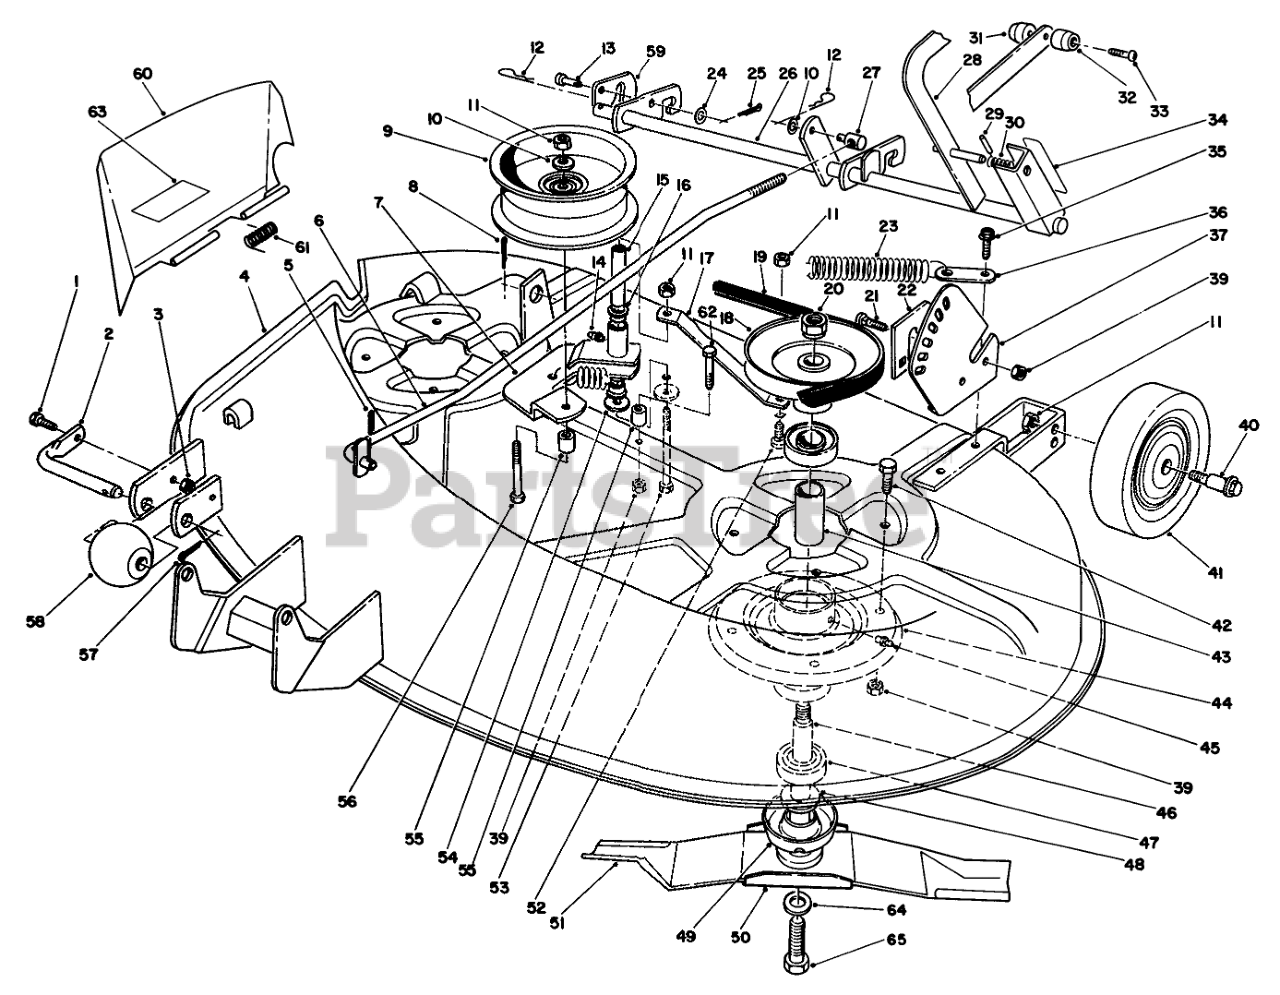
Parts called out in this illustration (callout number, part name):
1	SCREW-HH
2	SHAFT-ROLLER
3	NUT-LOCK, NI
4	DECK W/DECALS
5	PIN-SPRING
6	WLDMT-HEIGHT ADJ R
7	WLDMT-IDLER ARM R
8	PIN-COTTER
9	PULLEY-IDLER
10	WASHER-FLAT
11	NUT-LOCK, NI
12	Hairpin Cotter
14	FITTING-GREASE
15	SPACER
16	BUSHING
17	BRACE R
18	PULLEY R
19	BELT-V
20	Nut
21	BOLT-CARR
22	PLATE-RETAINING R
23	SPRING-EXTENSION
24	Washer
25	PIN-COTTER
26	WLDMT-HEIGHT ADJ R
27	STUD-TRUNION
28	WLDMT-LIFT LEVER R
29	PIN-SPIROL
30	SPRING-COMPRESSION
31	KNOB
32	KNOB
33	BOLT-4
34	DECAL-HOC
35	Bolt
36	Lever
37	QUADRANT R
39	NUT-LOCK, NI
40	BOLT-WHEEL
41	WHEEL-DECK
42	SCREW-HH
43	SPACER
44	Housing-Spindle
45	ZERK FITTING
46	SHAFT-SPINDLE
47	BEARING-BALL
48	SPACER-HARDNED
49	SHIELD-BEARING
50	SPACER-SPINDLE
51	Blade
52	BOLT-CARR
53	SCREW-HH
54	WASHER
55	SPACER
56	SCREW-HH
57	PIN-COTTER
58	ROLLER
59	LATCH B
60	DEFLECTOR W/ DECAL
61	SPRING-TORSION
62	SCREW-HH
63	DECAL-DANGER, THROWN OBJECT
64	WASHER-BELLEVILLE
65	SCREW-HH
